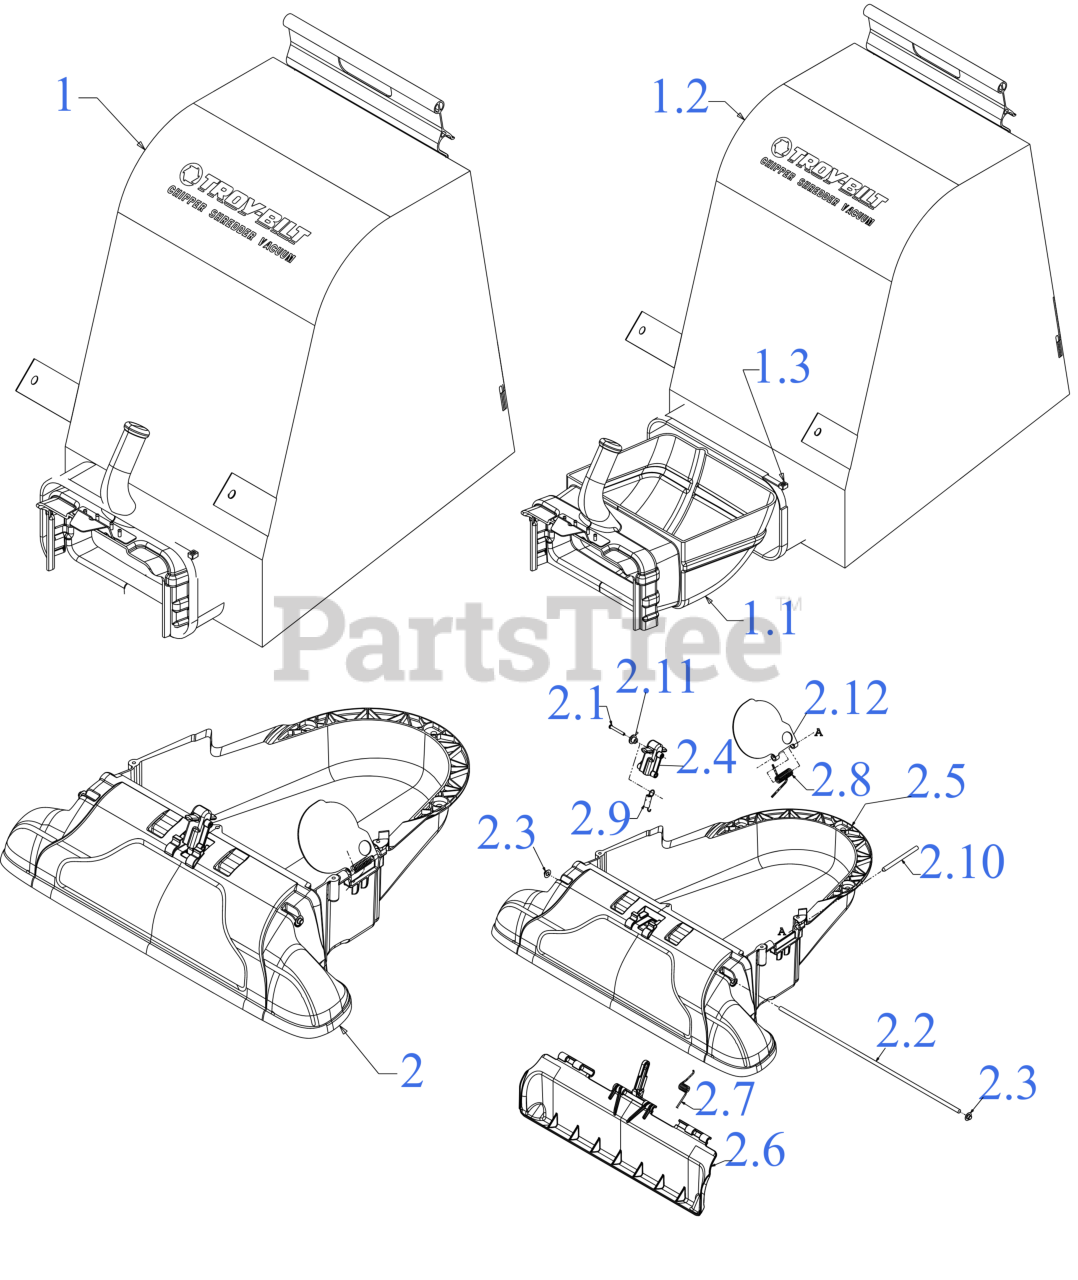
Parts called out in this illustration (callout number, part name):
1	CHUTE & BAG ASSEMBLY (TROY BILT)
1.1	CHUTE DISCHARGE ASSEMBLY
1.2	BAG ASSEMBLY
1.3	CABLE TIE 42IN LG
2	NOZZLE ASSEMBLY
2.1	SCREW #8-18 x 1.250
2.2	PIVOT ROD .25X16
2.5	NOZZLE ASSEMBLY
2.6	NOZZLE DOOR
2.7	TORSION SPRING
2.8	TORSION SPRING
2.9	EXTENSION SPRING
2.10	HINGE PIN .250DIA x 3.25
2.11	SHOULDER SPACER .21X.31 060 SER
2.12	BASE ADAPTER DOOR
